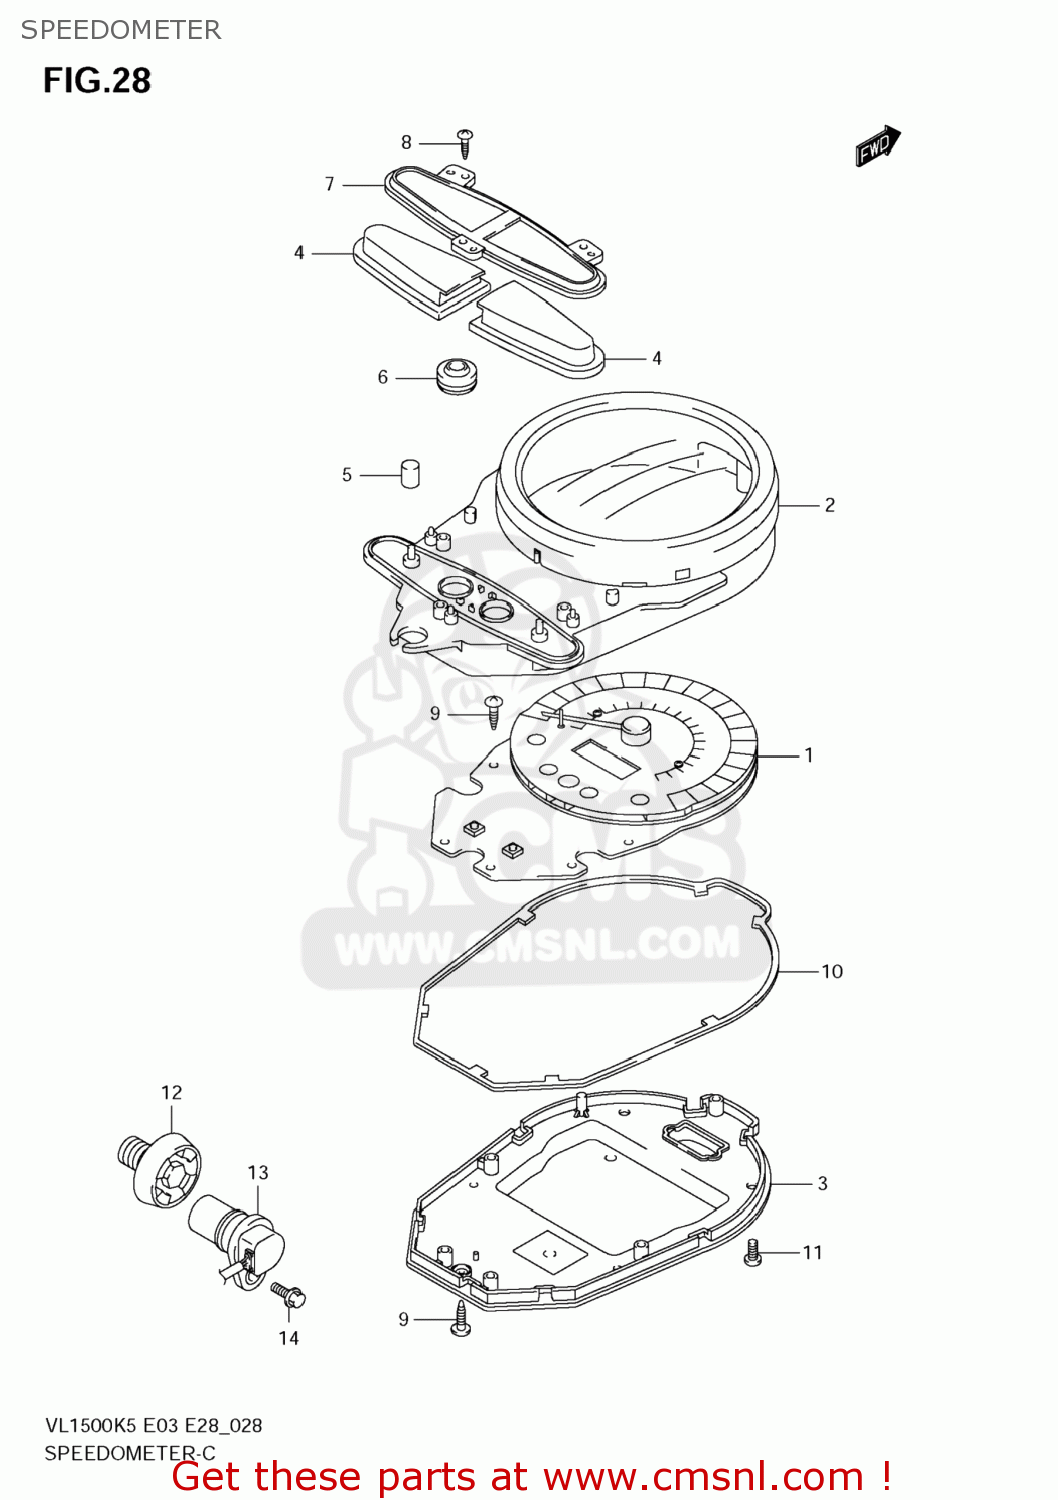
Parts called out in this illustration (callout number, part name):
1	SPEEDOMETER
2	CASE,UPR
3	CASE,LWR
4	SWITCH,SELECT
5	CUSHION
6	KNOB
7	PLATE,KNOB
8	SCREW
9	SCREW(3X10)
10	GASKET,METER CASE (NAS)
11	BOLT
12	ROTOR,SPEED
13	SENSOR,SPEED
14	BOLT(6X16)
